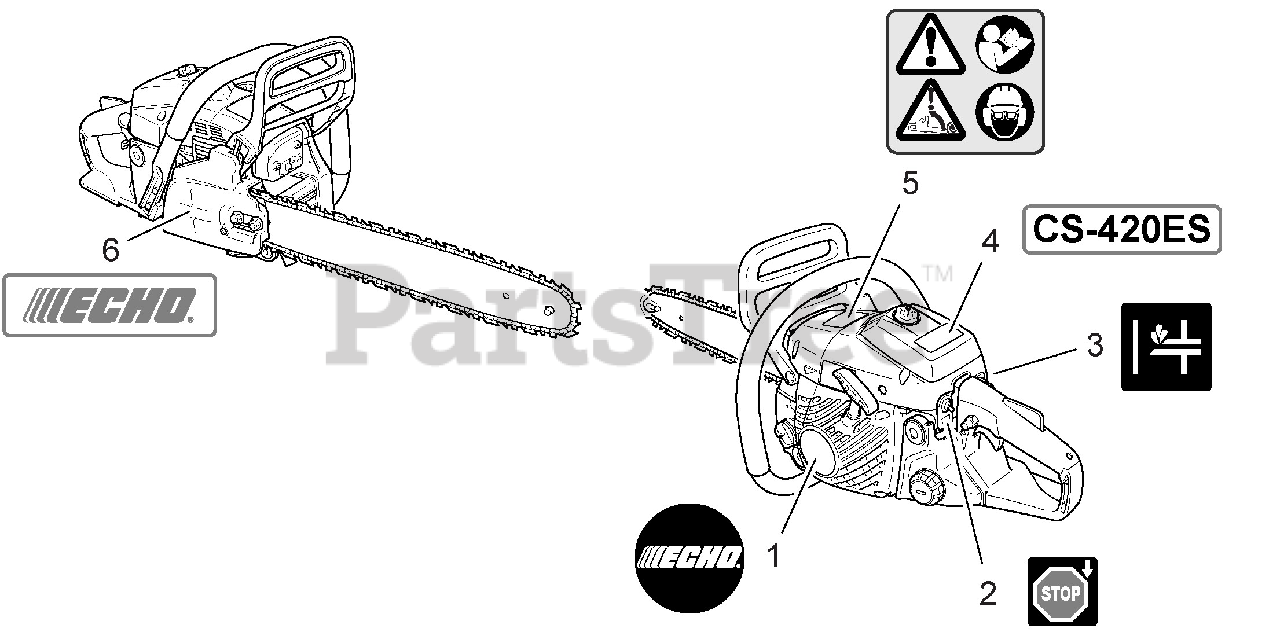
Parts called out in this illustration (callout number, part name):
1	LABEL - ECHO
2	LABEL - STOP
3	LABEL - PURGE PUMP
4	LABEL - MODEL CS-420ES
5	LABEL - CAUTION
6	LABEL - ECHO
